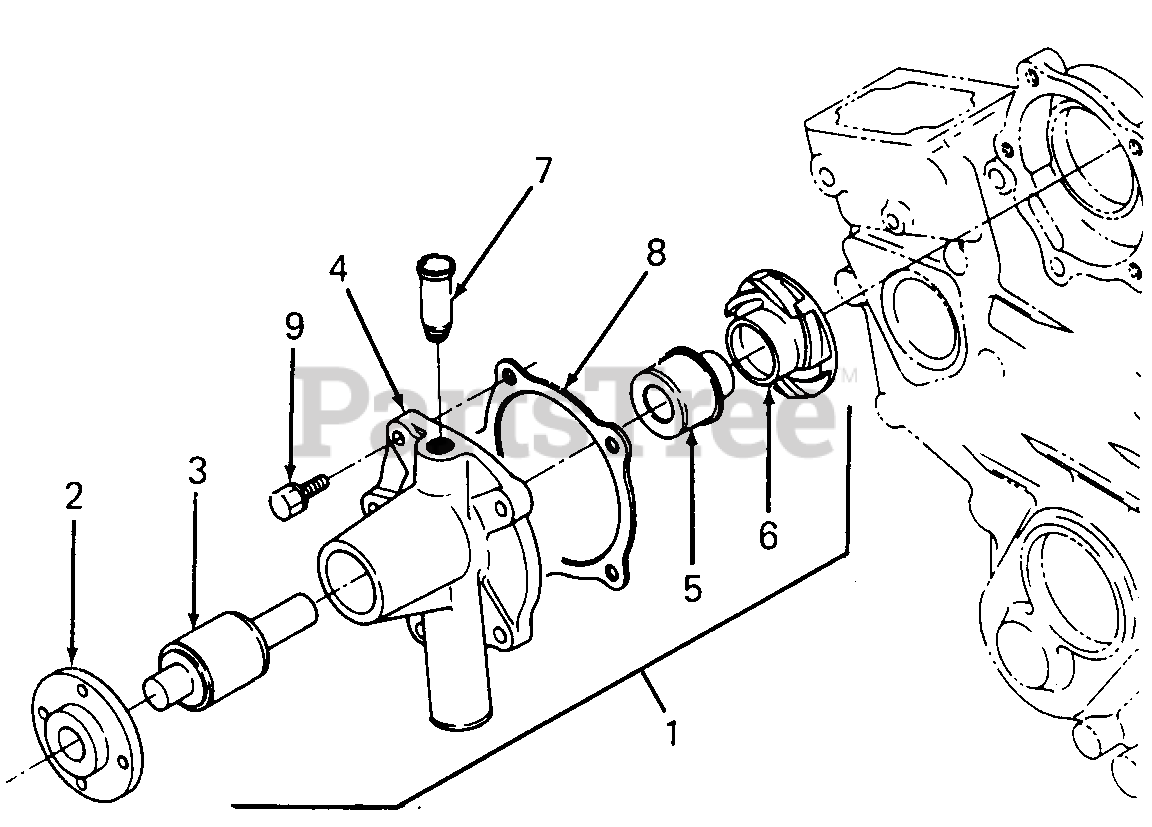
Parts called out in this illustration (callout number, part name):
1	Pump, Water
2	Flange, Water Pump
6	Impeller, Water Pump
7	Pipe, Water Return - 1
8	Gasket, Water Pump
9	Screw, Hex Cap w/Washer
